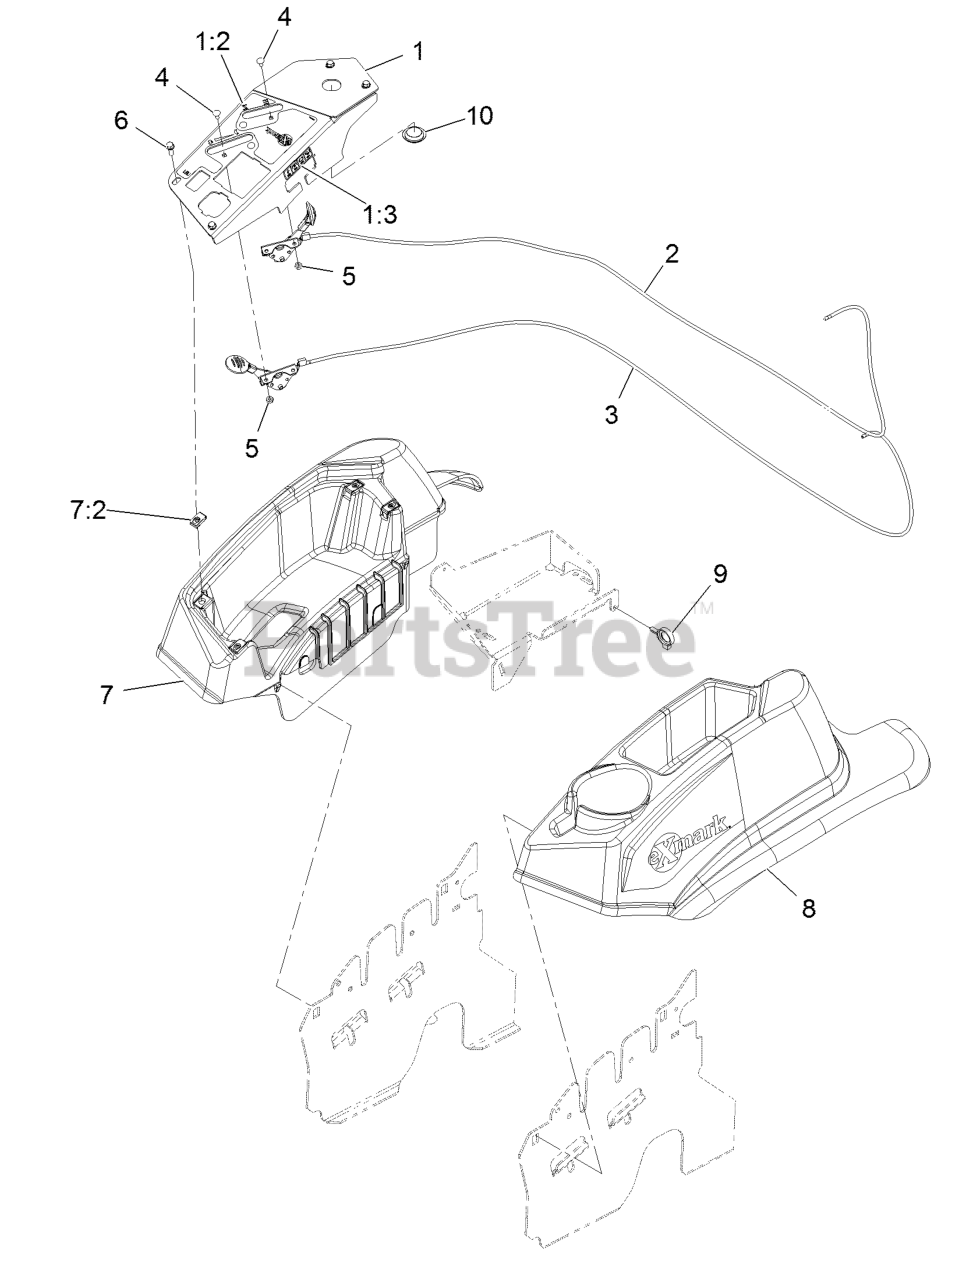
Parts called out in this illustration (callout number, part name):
1	CONSOLE,PANEL W/DECAL
1:2	DECAL-CONTROL PANEL NON-E
1:3	DECAL-FUSES
2	ASM, CHOKE CABLE
3	ASM,THROTTLE CABLE
4	BOLT-CARR
5	NUT-LOCK, NI
6	SCREW-HWH
7	CONSOLE,RH AS ASM
7:2	Nut-Retainer-Panel 1/4-20
8	CONSOLE, LH AS
9	CLAMP-HOSE
10	PLUG-PLASTIC
